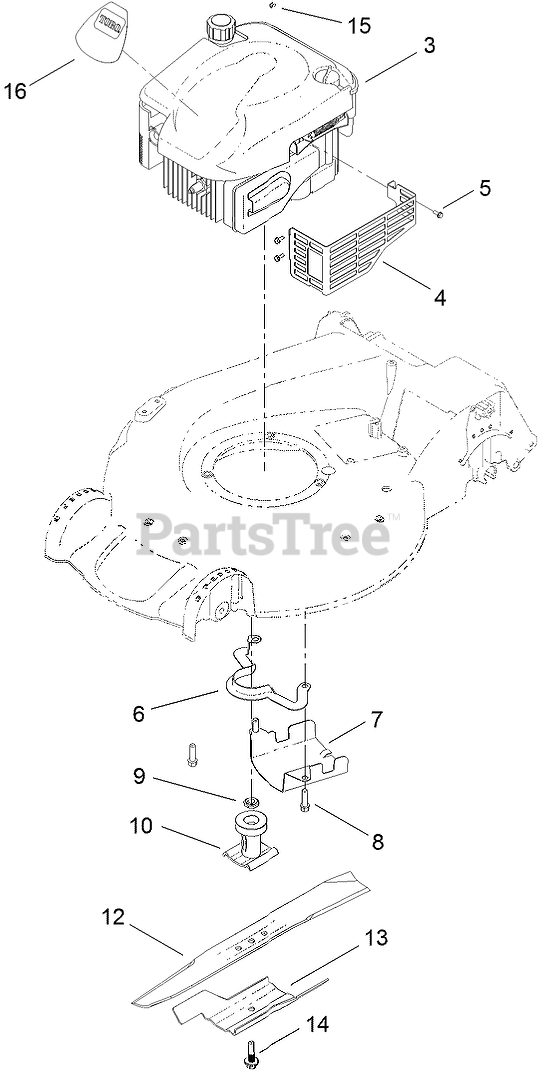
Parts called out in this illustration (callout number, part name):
4	SHIELD-MUFFLER
5	SCREW-TAPTITE
6	GUIDE-BELT
7	SHIELD-GRASS
8	SCREW-TAPTITE
9	Spacer-Driver
10	DRIVER-BLADE
12	BLADE-RECYCLING
13	Accelerator-Blade
14	BOLT-BLADE
15	STOP-ROPE
16	DECAL-SHROUD
